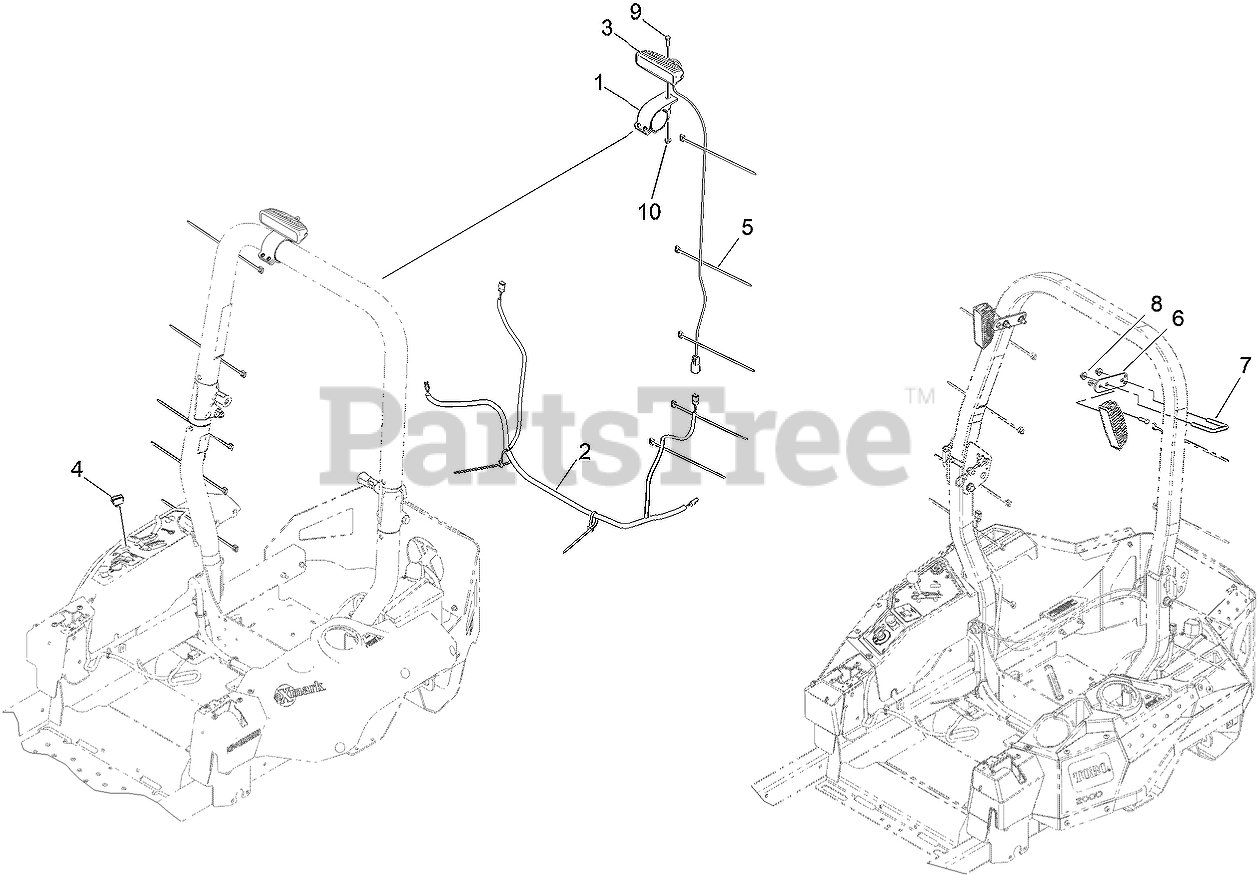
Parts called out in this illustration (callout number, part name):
1	CLAMP-TUBE
2	HARNESS-WIRE
3	LIGHT-LED
4	SWITCH-ROCKER
5	TIE-PLASTIC
6	PLATE-LIGHT MOUNT
7	U-BOLT
8	NUT-HF, NI
9	SCREW-HH
10	NUT-HEX FLANGE
